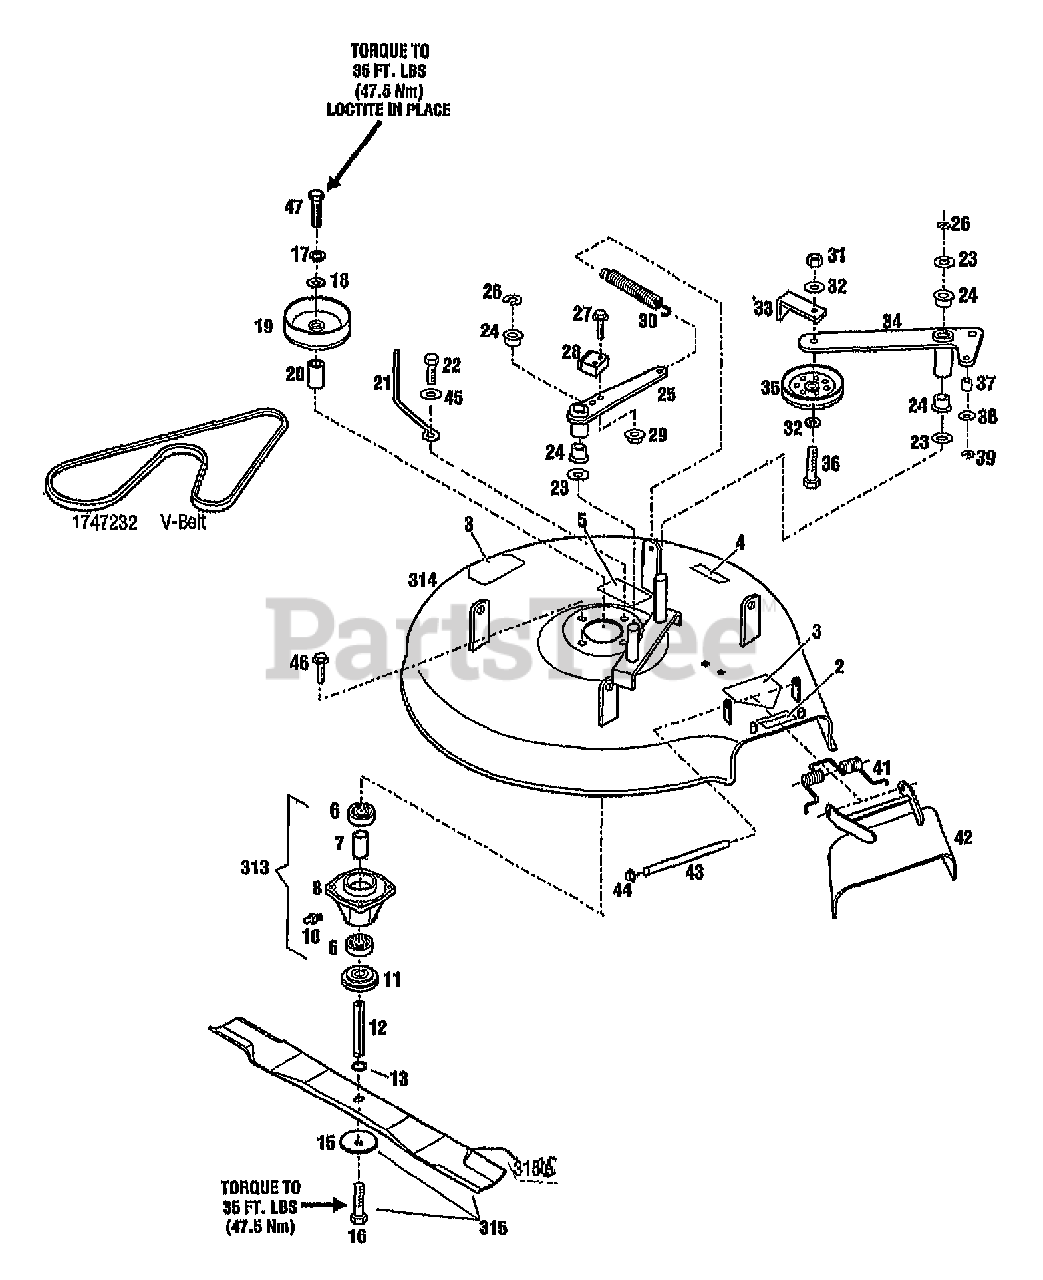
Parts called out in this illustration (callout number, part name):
2	DECAL-DANGER
3	DECAL-OPEI CAUTION
4	DECAL-22" CUT {34037,34036}
4	DECAL-26" CUT {34038,34039}
5	DECAL-CAUTION PINCH POINT
6	BEARING-BALL
8	HOUSING-SPINDLE
10	FITTING-GREASE 1/4-28X2.00
11	SPACER-BLADE
12	SPINDLE-SHAFT LONG H/T
13	RING-RETAINING EXT .694 ID
15	WASHER-LK CONICAL .49 ID
16	SCR-HH 1/2-14X1.00
17	WASHER-LK .438 ZP
18	WASHER-1.37X.453X.179 ZP
19	ASSM-SHEAVE
20	SPACER-DR PULLEY HW MWR
21	GUIDE-BELT
22	SCR-HFLK 5/16-18X1.25
23	WASHER-THRUST 1.1X.76X.05
24	BUSHING-NYLON
25	ASSM-BRAKE ARM
26	RING-RETAIN EXT .707 ID
27	SCR-HW M10-24X1.25 (INCL. WASHER)
28	PAD-BRAKE
29	NUT W/LKWASHER 10-24 ZP
30	SPRING
31	NUT-H/LK 3/8-16
32	WASHER-FLAT 3/8 SAE
33	GUIDE-BELT HW MWR
34	ASSM-IDLER ARM
35	IDLER 4" B-GROOVE
36	SCR-HH 3/8-16X1.75 G5 ZP
37	BEARING-BALL
38	WASHER-FLAT 1/4 SAE
39	RING-RETAINING
41	SPRING-TORSION
42	ASSM-HINGED DEFLECTOR
43	ROD-HINGE PIN
44	NUT-PUSH 3/8 ZP
45	WASHER-FLAT 5/16 SAE
46	SCR-HFLK 5/16-18X.75
47	SCR-HH 7/16-14X1.25
313	ASSM-MOWER SPINDLE (INCL. 6-8 & 10)
314	ASSM-DECK 22" {34037,34036}(INCL. DECALS)
314	ASSM-DECK 26" {34038,34039}(INCL. DECALS)
315	KIT-BLADE 22" (INCL. 15 & 16)
315	KIT-BLADE 26" (INCL. 15 & 16)
315A	BLADE-22"
315A	BLADE-26"
322	LOCTITE-242 (.5 ML TUBE)
